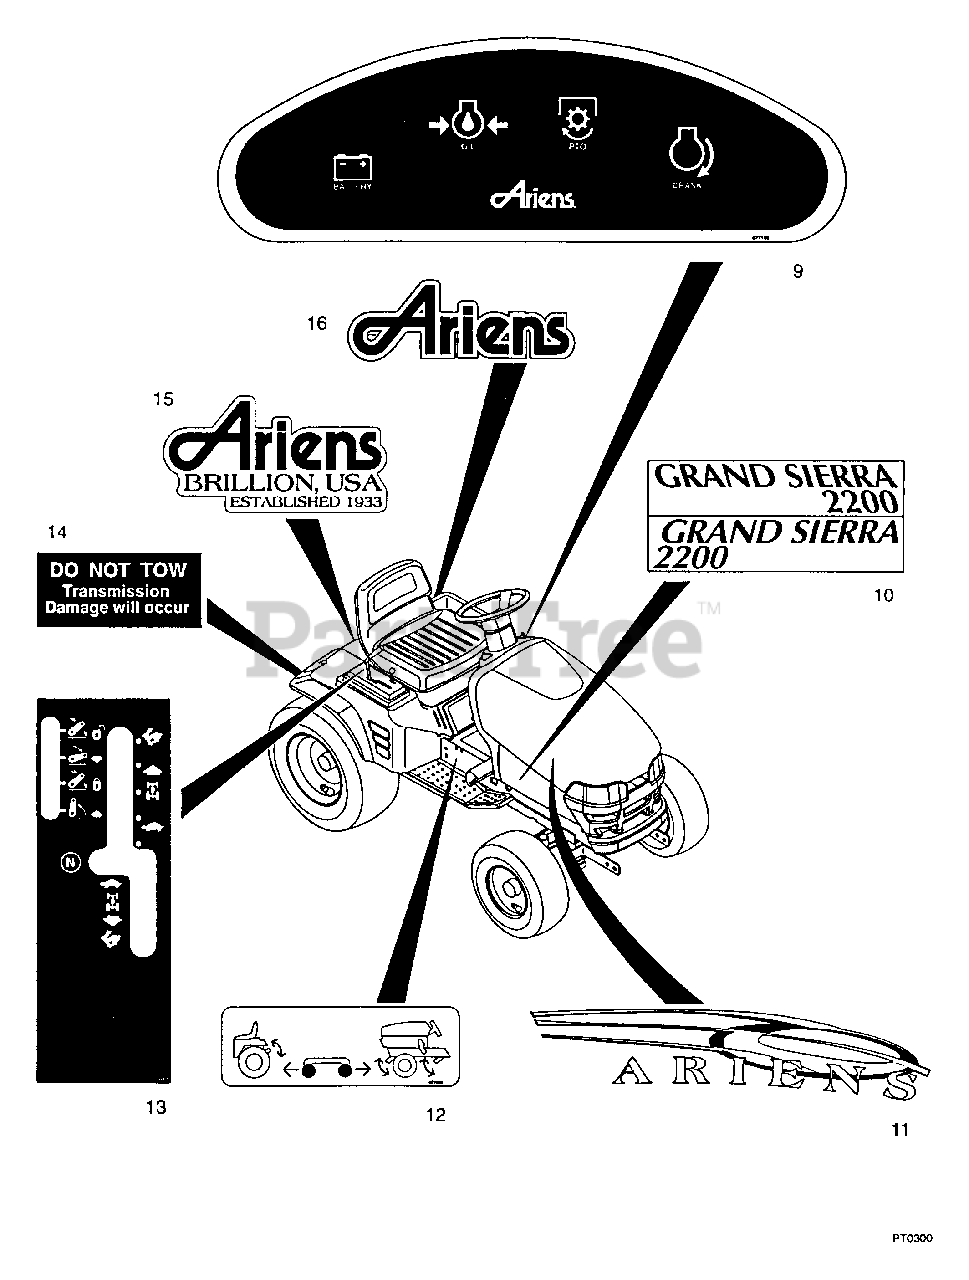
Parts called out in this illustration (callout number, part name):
9	DECAL- DASH W/ LIGHTS
10	DECAL - GRAND SIERRA 2200 - L
11	DECAL- ARIENS HOOD LOGO- R
12	DECAL - LIFT SELECTOR
13	DECAL, CONTROL CONSOLE
14	TRANSMISSION DECAL
15	DECAL- ARIENS EST. 1933
16	DECAL-ARIENS
